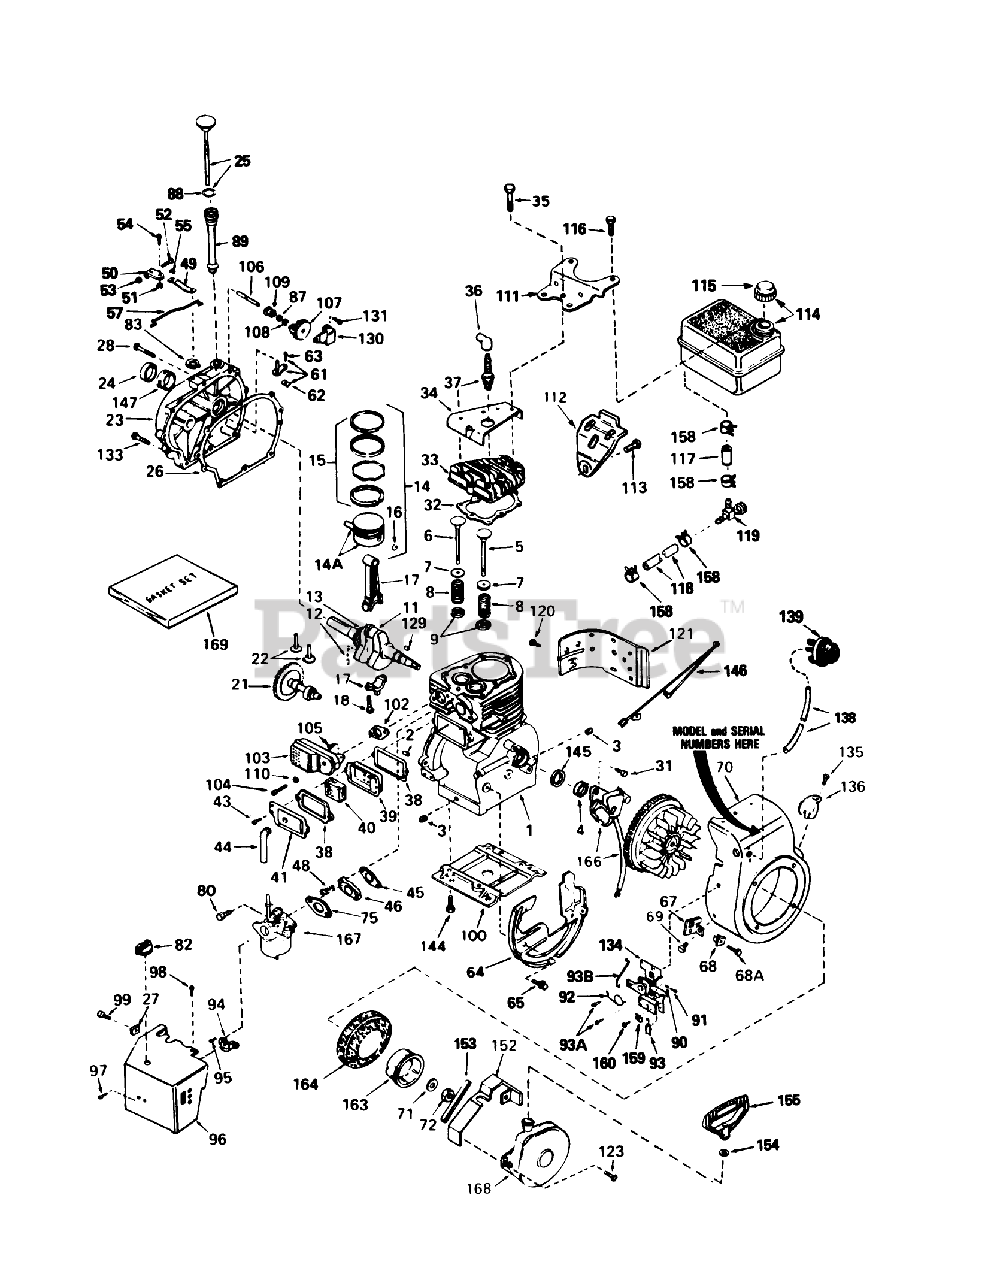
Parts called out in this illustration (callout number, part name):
1	Cylinder Assy. (Incl. Ref. #2, 3 4)
2	Pin-Dowel
3	Plug-Drain, Oil (SQH 1/4-18)
4	Oil Seal
5	Valve, Intake (Standard)(Incl. No. 9)
5	Valve, Intake (1/32" oversize)(Incl. No. 9)
6	Valve, Exhaust (Standard)(Incl. No. 9)
6	Valve, Exhaust (1/32" oversize)(Incl. No. 9)
7	Cap-Spring, Valve
8	Spring-Valve
9	Keeper-Spring, Valve
11	63579 ADN.CHAIN TIL
12	Pin, Groove
13	Gear-Crankshaft
14	Piston, Pin Ring Assy. (Std.)(Incl. Ref. #14A, 15 16)
14	Piston, Pin Ring Assy. (.010 Oversize)(Incl. Ref. #14A, 15 16)
14	Piston, Pin Ring Assy. (.020 Oversize)(Incl. Ref. #14A,15 16)
14A	Piston Pin Assy. (Std.)(Incl. Ref. #16)
14A	Piston Pin Assy. (.010 Oversize)(Incl. Ref. #16)
14A	Piston Pin Assy. (.020 Oversize)(Incl. Ref. #16)
15	Ring Set (Std.)
15	Ring Set (.020" OS)
15	Ring Set (.010" OS)
17	Rod Assy., Connecting (Incl. Ref. #18)
18	Bolt, Connecting Rod
21	Camshaft, BCR
22	Lifter-Valve
23	Cover, Cylinder (Incl. Nos. 24 106)
24	Oil Seal
25	Dipstick, Oil (Incl. Ref. #88)
26	Gasket-Cover, Cylinder
27	Nut-U Type
28	Screw (1/4-20 x 1-1/4)
31	Screw
32	Gasket-Head, Cylinder
33	CYLINDER HEAD
34	Cover-Head, Cylinder
35	Screw (5/16-18 X 2-1/2)
36	Cover-Spark Plug
37	Plug, Spark (J17LM or equiv.)
37	Plug, Spark (Champion RCJ-8)
38	Gasket-Breather
39	Body-Breather
40	Element-Breather
41	Cover-Valve
43	Screw
44	Tube-Breather
45	Gasket-Intake
46	481-1279 SENATOR RO
48	Screw
49	Lever-Governor
50	Clamp-Lever, Governor
51	Nut-Lock
52	Screw
53	Nut-Lock
54	Screw
55	Washer-Lock
57	Governor Link
61	Rod, Governor (Incl. Nos.62 63)
62	Yoke-Governor
63	Screw (6-40x5/16)
64	Baffle Blower Housing
65	Screw (1/4-20x19/32)
67	Bracket
68	Grommet
68A	Screw
69	Screw, Hex Hd.
70	Housing, Blower (Incl. Ref. #135 136)
71	Washer-Belleville
75	Gasket-Carburetor
80	Screw-Hex Hd.
82	Knob-Control
83	Ring-Retaining
87	Washer-Flat
88	O-Ring
89	Tube Fill
90	Spring-Compression
91	Screw
92	Spring-Throttle
93	Terminal
93A	Screw (10-32 x 1/2)
93B	Link-Throttle
94	Bracket-Choke
95	Screw (10-32 x 1/2)
96	Carburetor Cover
97	Screw (8-32 X 5/16)
98	Screw (10-32x1/2)
99	Screw (8-32 x 3/8)
100	Base Engine
102	Gasket Exhaust
103	Muffler
104	Screw (5/16-18 X 2)
105	Screw
106	Shaft-Governor
107	Governor Gear ASM
108	Ring-Retaining
109	Spool-Governor
110	Washer
111	Plate, Fuel Tank Mounting
112	Bracket, Fuel Tank Mounting
113	Screw (1/4-20x19/32)
114	481-1261 SENATOR TI
115	Cap, Fuel
116	Screw (1/4-15x7/8)
117	Line-Fuel
118	Line-Fuel (8.62)
119	Valve-Shut Off
120	Screw
121	Emnsion, Blower Housing
123	Screw
129	Key-Flywheel
130	Bracket, Governor
131	Screw (10-24x1/2)
133	Screw
134	Control Assy., Remote Speed (Incl. Ref. #90 thru 93)
135	Screw (8-32 x 3/8)
136	Screw
138	Line-Primer
139	Primer Assy.
144	Screw
145	Gasket Stator
146	Wire, Ground
147	Bushing-Crankshaft
152	Guard-Starter
153	Seal, Snowguard
154	Washer
155	Handle-Starter, Mitten Grip
158	Clamp-Line, Fuel
159	Conduit
160	Screw (10-32 x 3/8)
163	Cup-Starter
164	Screen-Starter
166	Magneto(The complete magneto is not available as an assembly. The magneto number is shown for reference purposes only. Order component parts individually,as shown in parts list.)
167	Carburetor (Incl. Ref. #75)
168	Starter Assy.-Rewind
169	Gasket Set (Incl. Items Marked *)
